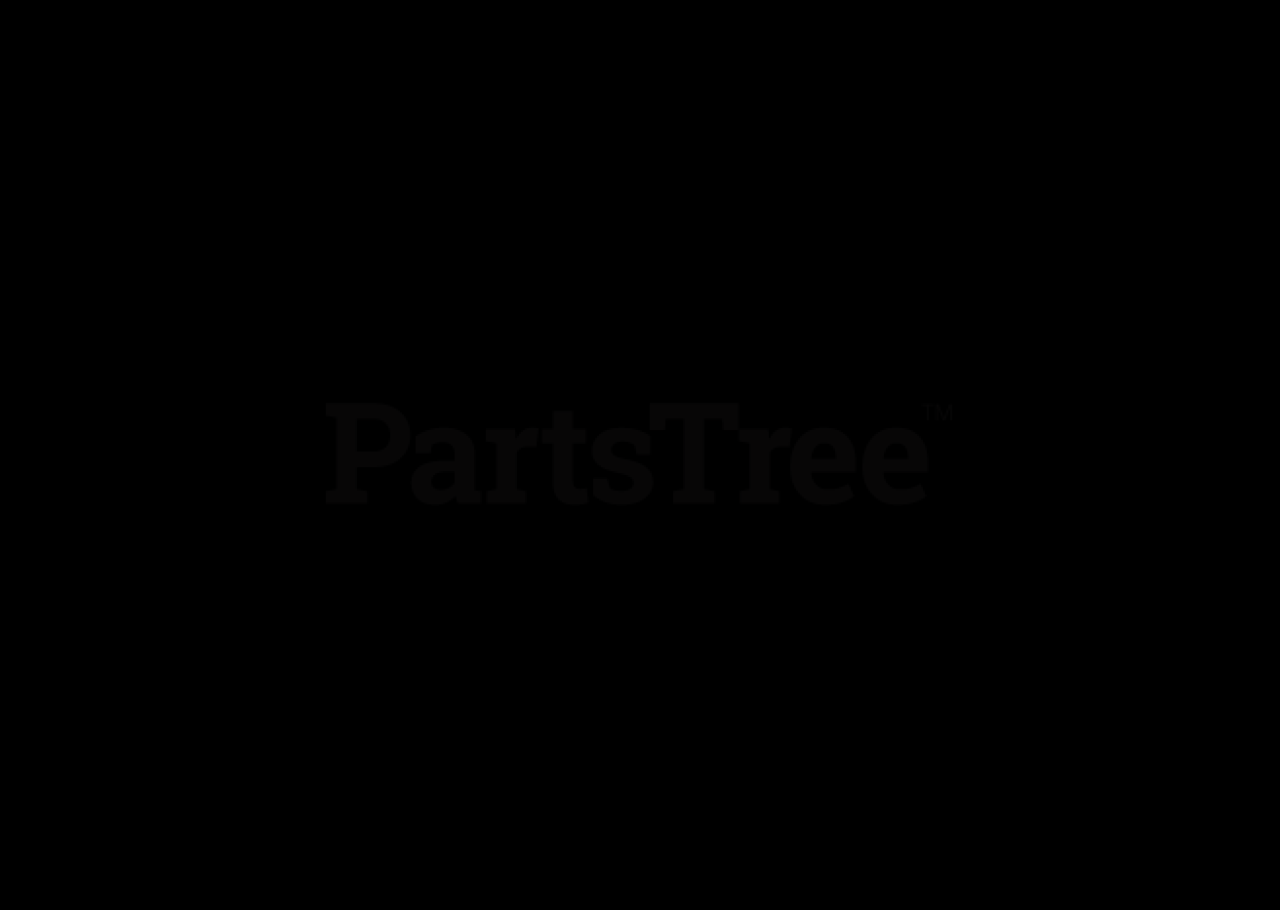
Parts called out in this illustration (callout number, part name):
1	FUEL SYSTEM KIT - YOUCAN™
2	PIPE, FUEL 3×6×80 CLEAR
3	VENT ASSY
4	CLIP Ø6
5	PIPE, FUEL 3×5×90 BLACK
6	PIPE, FUEL 3×5×74 BLACK
7	GROMMET, FUEL Ø5
8	CONNECTOR, PIPE Ø5ר3.5
9	PIPE, FUEL 3×5×130 BLACK
10	FILTER, FUEL
11	GASKET, FUEL CAP
12	CAP ASSY, FUEL
13	GASKET, FUEL CAP
14	CONNECTOR, CAP L= 123
15	TANK ASSY, FUEL
16	COLLAR 5
17	BOLT, TORX 5×20
18	TUNE-UP KIT - YOUCAN™
